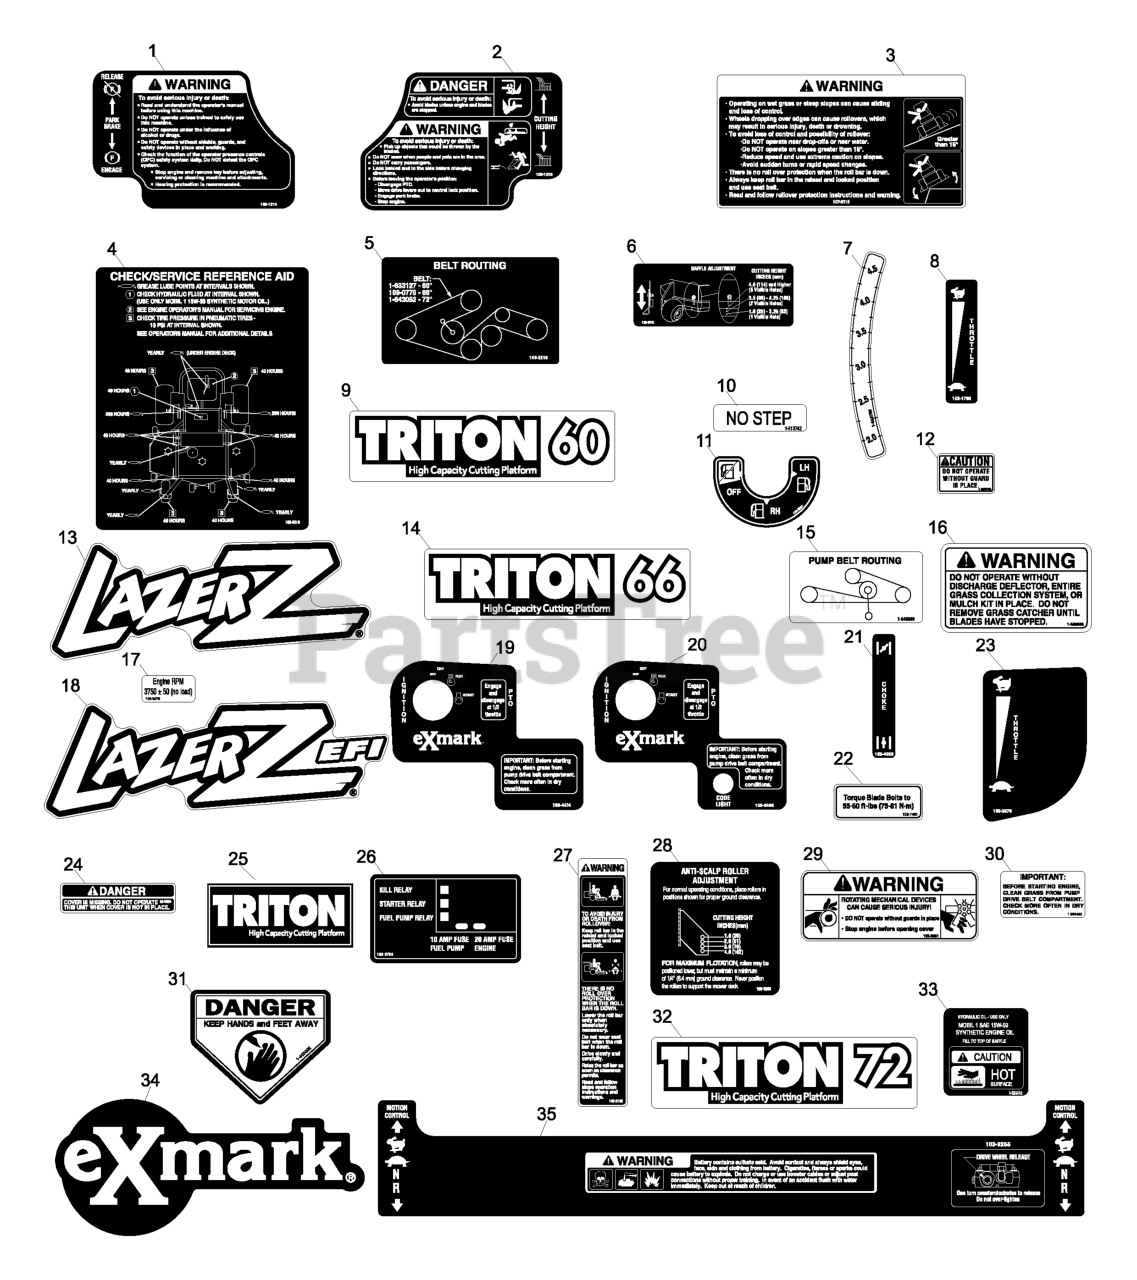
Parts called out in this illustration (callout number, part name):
1	DECAL,PARK BRAKE
2	DECAL,DECK HEIGHT
3	DECAL-WARNING
4	DECAL,CHECK SERVICE LZ
5	DECAL,BELT ROUTING
6	DECAL,BAFFLE ADJUSTMENT
7	DECAL-HEIGHT, DECK
8	DECAL,THROTTLE ONLY
9	DECAL,TRITON 60
10	DECAL,NO STEP
11	DECAL-VALVE, FUEL
12	DECAL-GUARD
13	DECAL,LAZER MODEL
14	DECAL,TRITON 66
15	DECAL-ROUTING, BELT
16	DECAL-WARNING, DISCHARGE
18	DECAL,EFI
19	DECAL,IGNITION/PTO
20	DECAL,IGNITION/PTO EFI
21	DECAL,CHOKE
24	DECAL-COVER, MISSING
27	DECAL-WARNING, FOLDING RO
28	DECAL,ANTISCALP
29	DECAL-DEVICES, ROTATING
30	DECAL-IMPORTANT
31	DECAL-DANGER
32	DECAL,TRITON 72
34	DECAL,EXMARK LOGO
35	DECAL, TOP CONSOLE LZ
